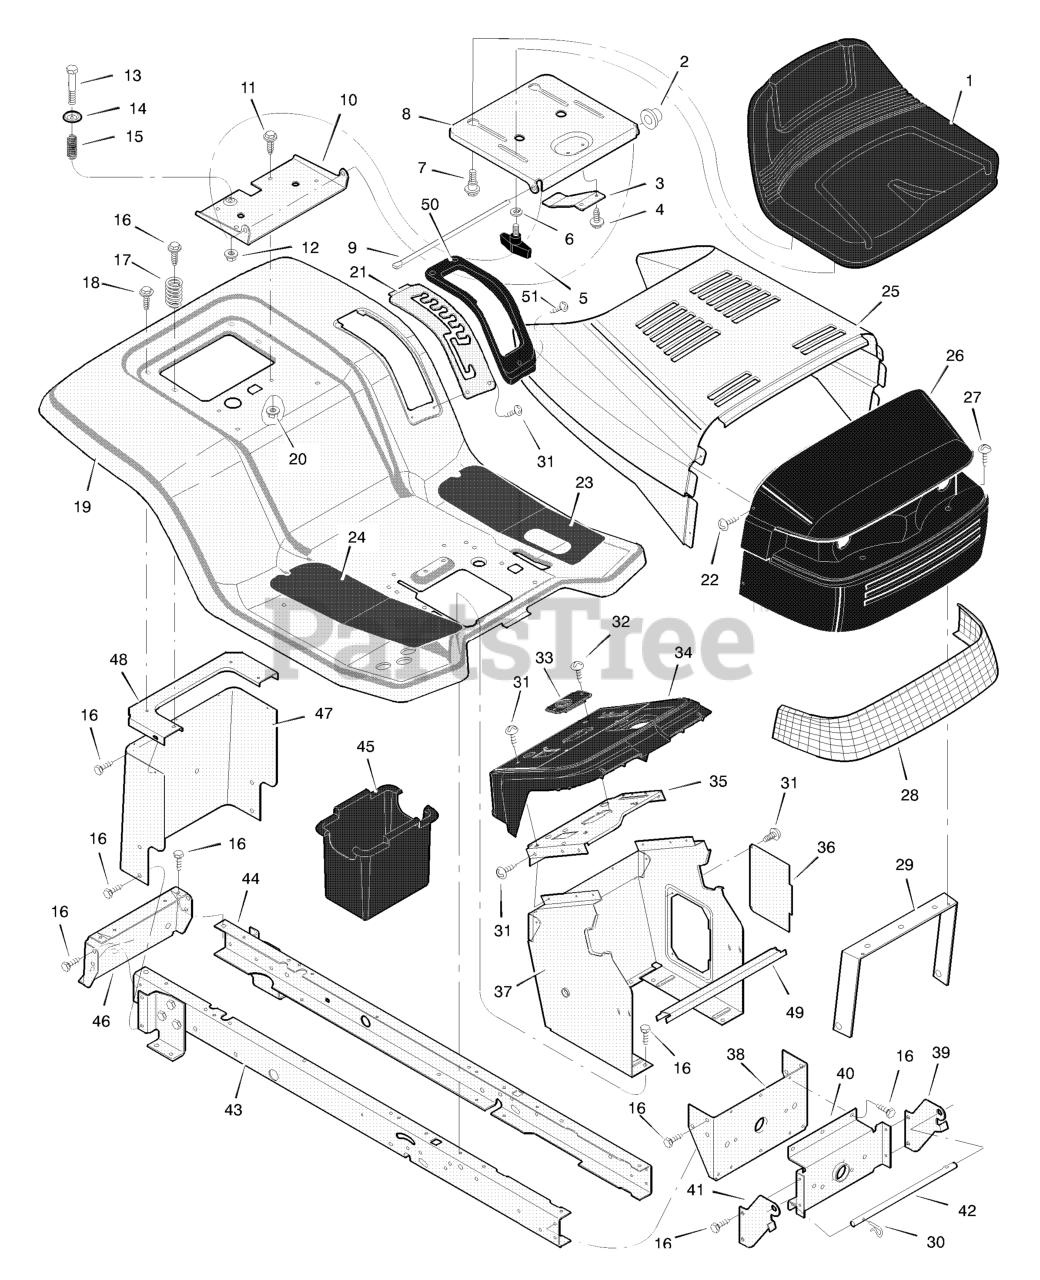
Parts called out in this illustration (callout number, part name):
1	Seat
2	Cap, Push On
5	Bolt, Wing
6	Washer
7	Bolt, Shoulder
8	Support, Seat
9	Rod, Pivot
10	Bracket, Pivot
11	Bolt
13	Bolt, Shoulder
15	Spring
19	Deck, Seat
20	Nut
21	Plate, Index
23	Mat, Left
24	Mat, Right
25	Hood
26	Grille Assembly
29	Brace, Grille
30	Pin, Hair
31	Screw
33	Bearing, Steering
35	Plate, Dash
36	Panel, Access
37	Support, Dash
38	Bracket, Rear Hanger
39	Support, Left Grille
40	Axle, Hanger
41	Support, Right Grille
42	Rod, Pivot
43	Frame, Right
44	Frame, Left
45	Container, Battery
46	Plate, Hitch
47	Panel, Rear
48	Plate, Rear
